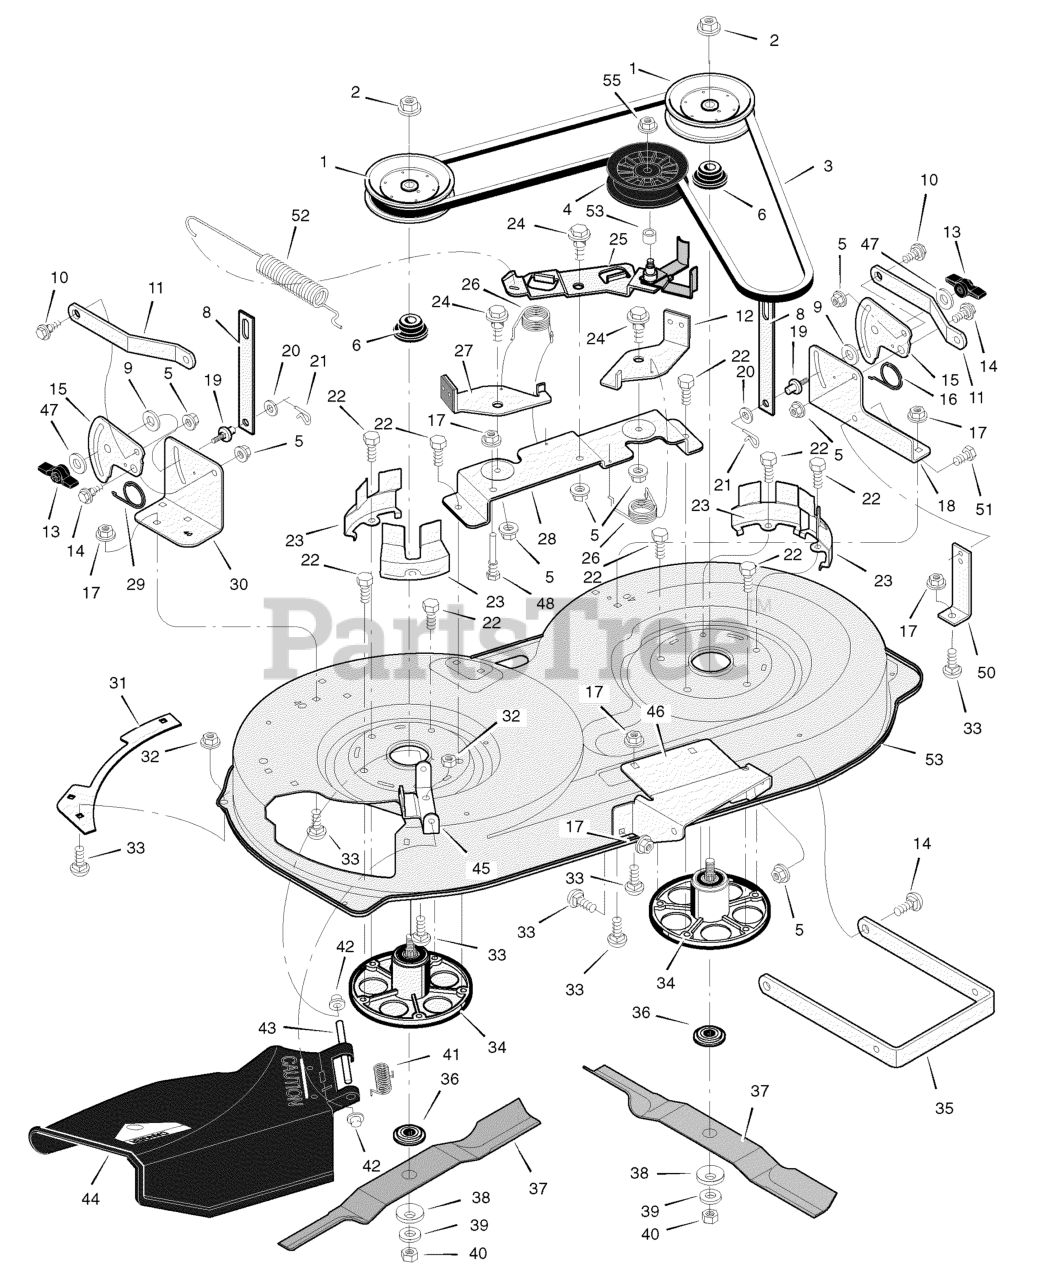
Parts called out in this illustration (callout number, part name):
1	Pulley, Jackshaft
2	Nut, Hex
3	Belt, Mower Drive
4	Pulley, Idler
5	Nut, Flange
6	Spacer, Pulley
8	Link, Lift
9	Pad, Friction
10	Bolt, Shoulder
11	Bracket, Suspension
12	Pad Assembly, Left Brake
14	Bolt, Shoulder
15	Plate, Suspension
16	Spring
17	Nut, Flange
18	Bracket, Suspension
19	Pin, Hanger
20	Washer
21	Pin, Cotter
22	Bolt
23	Cover, Pulley
24	Bolt, Shoulder
25	Arm, Idler
26	Spring
27	Pad Assembly, Right Brake
28	Bracket Assembly, Brake
29	Spring
30	Bracket, Suspension
32	Nut, Flange
33	Bolt, Carriage
34	Mandrell
35	Bracket, Suspension
36	Adapter, Blade
38	Washer
39	Washer
40	Nut
41	Spring
42	Cap, Push On
43	ROD, Deflector
44	Deflector Assembly
45	Bracket, Deflector
46	Bracket, Front Hanger
48	Guide, Belt
50	Bracket, Support
51	Screw
52	Spring, Extension
53	Spacer
54	Housing, Blade *
55	Nut, Flange
